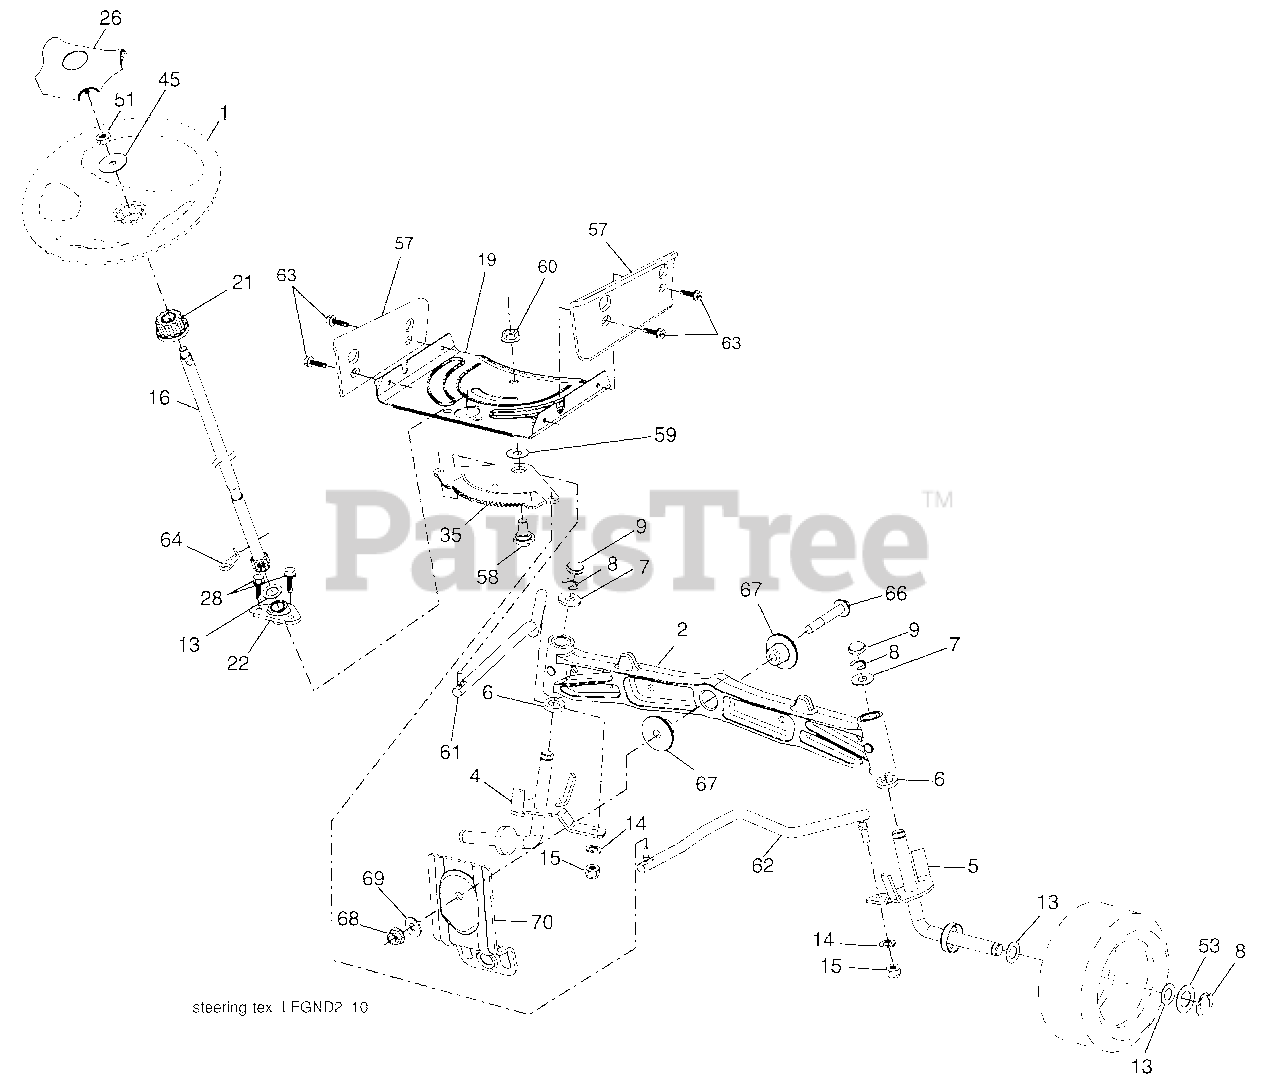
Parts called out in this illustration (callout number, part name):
1	Wheel, Steering
2	Axle Asm., Front
4	Spindle Asm., LH
5	Spindle Asm., RH
6	Bearing, Race Thrust Harden
7	Washer 25/32 x 1-5/8 x 16 Ga.
8	Ring, Clip #T5304-75
9	Cap, Spindle
13	Washer 25/32 x 1-1/4 x 16 Ga.
14	Washer, Lock Hvy Hlcl Spr 3/8
15	Nut, Crown Lock 3/8-24 unf
16	Shaft Steering
19	Plate Steering
21	Adapter, Wheel Steering
22	Bushing, Strg. Blk
26	Insert, Wheel Steering
28	Screw 3/8-16 x 3/4
35	Gear, Sector Plate
45	Washer 9/16 ID x 2-3/8 OD 12 Ga.
51	Nut Hex Jam Toplock 1/2-20 unf
53	Washer Hardened .793 x 1.637 x .060
57	Bracket Upstop
58	Bolt Shoulder Sector Pivot CFM
59	Washer Thrust Sector Steering
60	Nut Flange Lock 5/8-11
61	Draglink LH
62	Draglink, RH
63	Screw 5/16-18 x 3/4
64	Retainer Clip Spring Steering
66	Bolt Hex Fghd 7/16-14 x 3 Serr
67	Bushing PM Front Axle
68	Nut Lock Flange 7/16-14 Gr. 5
69	Washer 1.5 x .505 x .118
70	Bracket Deck Susp. Front
